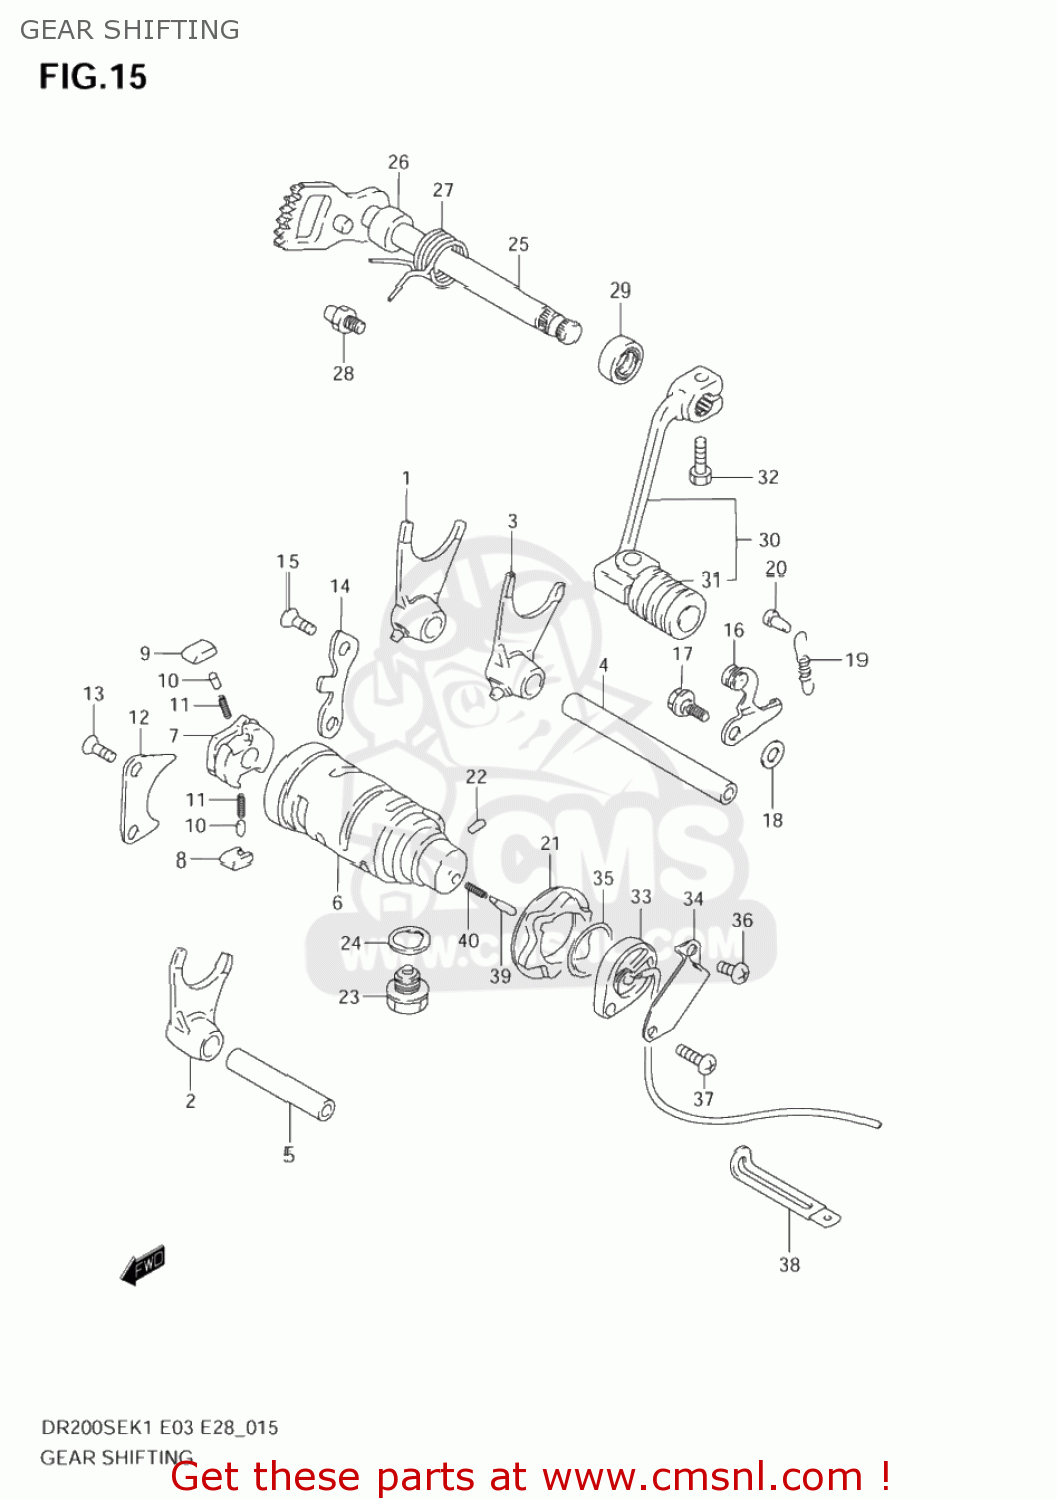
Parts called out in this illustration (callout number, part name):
1	FORK,GEAR SHIFT NO.1
2	FORK,GEAR SHIFT NO.2
3	FORK,GEAR SHIFT NO.3
4	SHAFT,GEAR SHIFT FORK(L:109)
5	SHAFT,GEAR SHIFT FORK NO.2
6	CAM,GEAR SHIFT
7	GEAR,GEAR SHIFT CAM DRIVEN
8	PAWL,GEAR SHIFT NO.1
9	PAWL,GEAR SHIFT NO.2
10	PIN(5X8)
11	SPRING
12	LIFTER,GEAR SHIFT POLE
13	SCREW
14	GUIDE,GEAR SHIFT CAM
15	SCREW
16	STOPPER,GEAR SHIFT CAM
17	BOLT(6X14.6)
18	WASHER
19	SPRING
20	RIVET
21	PLATE,GEAR SHIFT CAM STOPPER
22	PIN
23	PLUG (14X12)
24	GASKET(13.8X18.8X4.8) (NAS)
25	SHAFT,GEAR SHIFT
26	SPACER(12X20X15.3)
27	SPRING
28	STOPPER,GEAR SHIFT ARM
29	OIL SEAL
30	LEVER ASSY,GEAR SHIFT
31	RUBBER,GEAR SHIFT PEDAL
32	BOLT
33	BASE ASSY,NEUTRAL SW TERMINAL
34	PROTECTOR,GEAR SHIFT SW
35	O RING(D:2.4,ID:21.8)
36	SCREW
37	SCREW
38	CLAMP(L:45)
39	PIN(5X15.5)
40	SPRING
